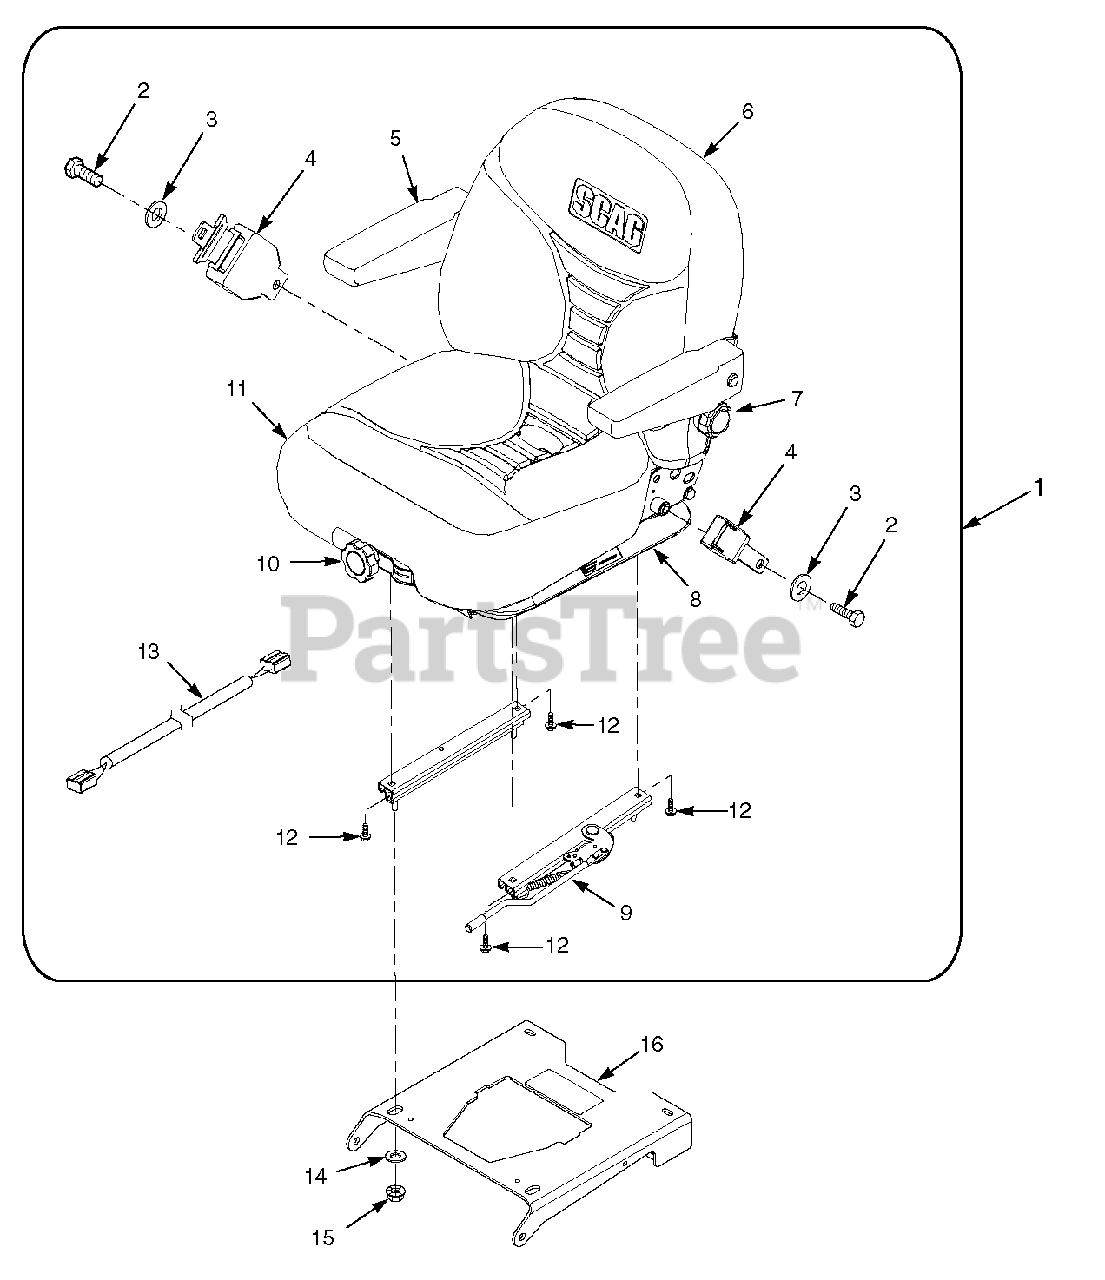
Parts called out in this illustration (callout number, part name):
1	Suspension Seat Assembly w/seat belt
2	Bolt, Hex Head 7/16-20 x 1"
3	Flatwasher, 7/16-.500 x 1.25 x .083
4	Retractable Seat Belt
5	Armrest Only
6	Back Cushion Kit
7	Lumbar Kit
8	Shock Absorber Kit
9	Seat Adjustment, Track Set
10	Weight Adjustment Kit
11	Seat Cushion Kit Seat Drain Kit
12	Bolt, Hex Head 5/16-18 x 1-3/4"
13	Wire Harness Adapter
14	Flatwasher, 3/8-.391 x .938 x .105
15	Nut, Serrated Flange 5/16-18
16	Seat Plate Weldment w/Decal
